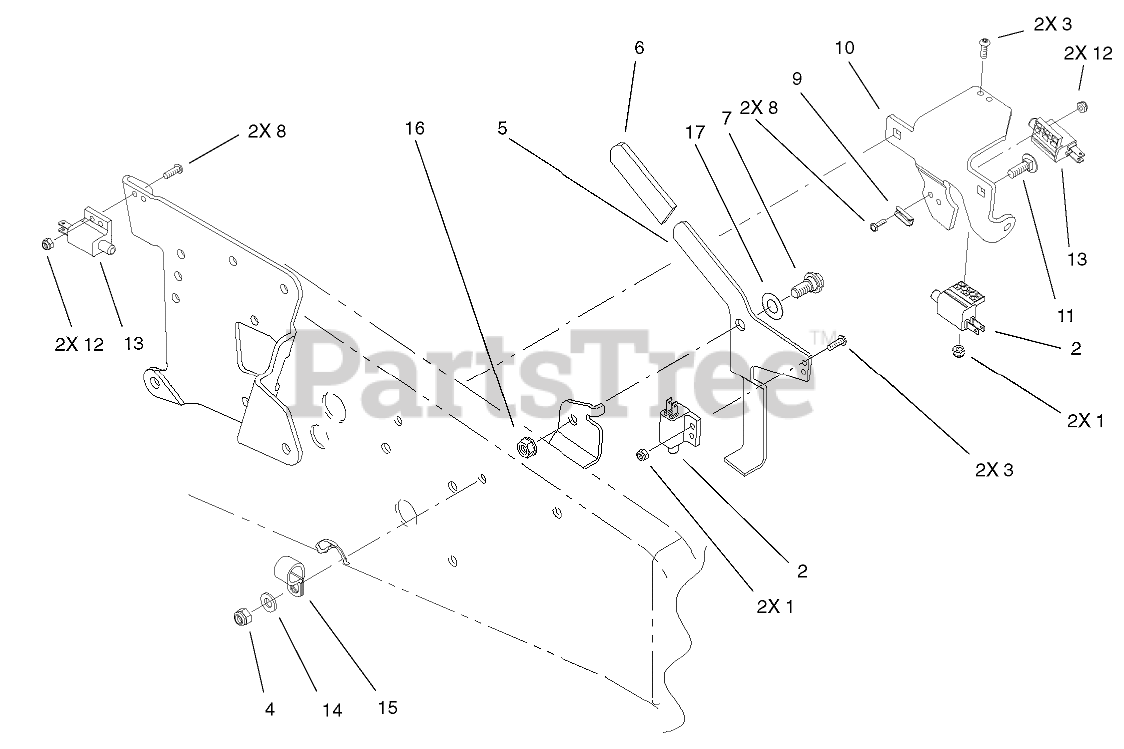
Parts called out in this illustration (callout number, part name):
1	NUT-LOCK, NI
2	SWITCH-POLE, SINGLE
3	SCREW-HSH
4	NUT-LOCK, NI
5	LATCH-BRAKE, PARKING
7	BOLT-SHOULDER
8	Screw
9	RETAINER-SCREW
10	BRACKET-SWITCH
11	SCREW-CARR
12	NUT-LOCK
13	SWITCH-POLE, SINGLE
14	WASHER-PLAIN
15	CLAMP - R
17	WASHER
